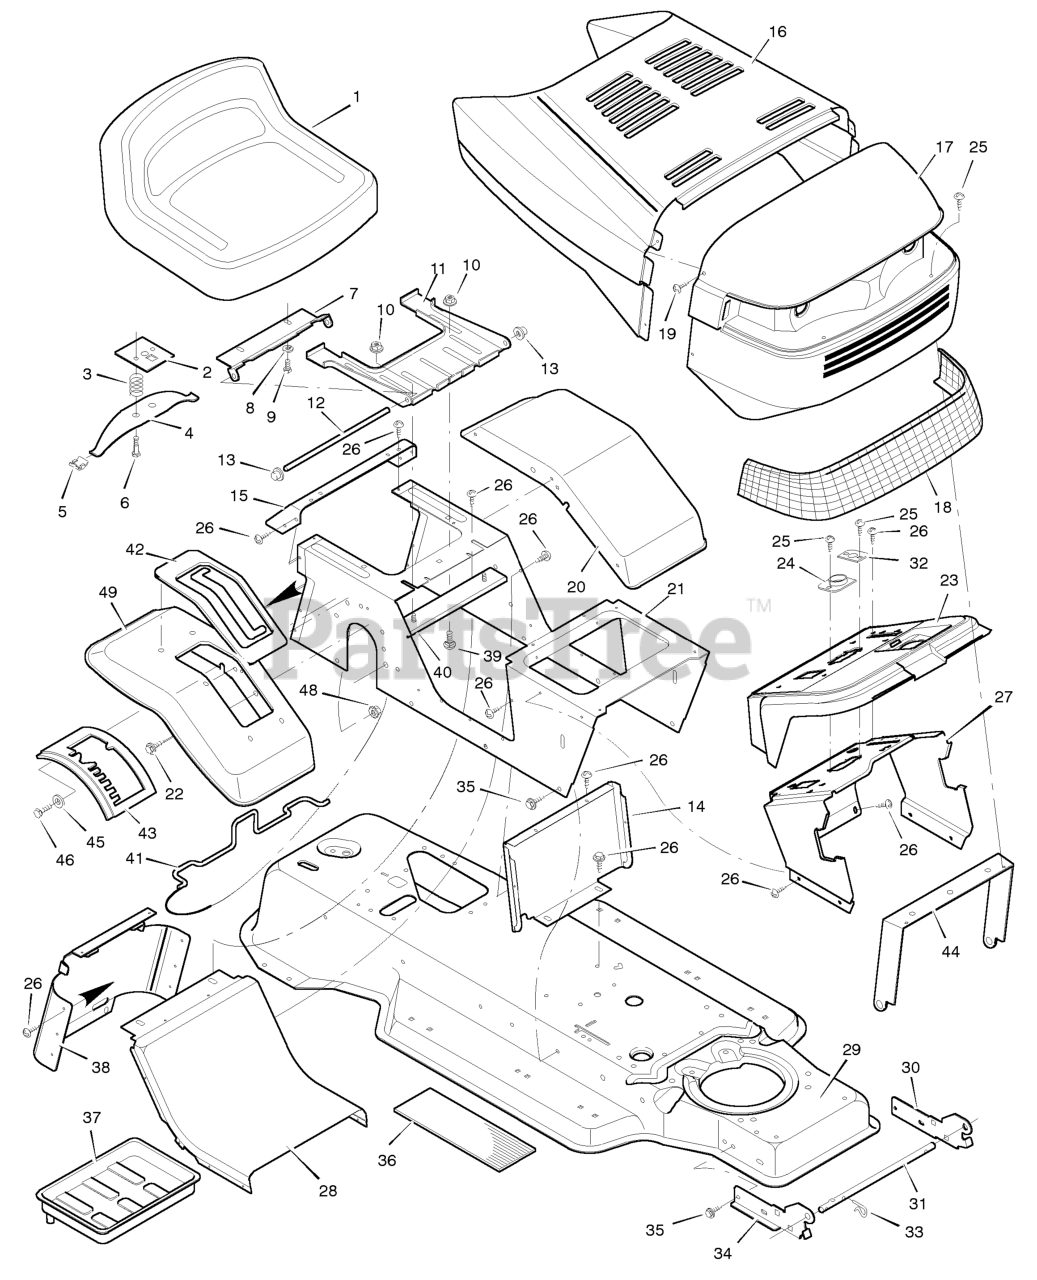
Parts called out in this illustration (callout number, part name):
2	Plate Assembly, Switch
3	Spring, Compression
4	Spring, Seat
5	Glide, Spring
6	Bolt, Shoulder
7	Support, Seat
8	Lockwasher
9	Bolt, Hex
10	Locknut, Flange
11	Bracket, Pivot
12	Rod, Pivot
13	Cap, Push On
14	Insert, Front
15	Fender, Apron
16	Hood
17	Grille Assembly
21	Console Assembly
23	Dash Panel
24	Bearing, Steering
26	Screw
27	Support, Dash
28	Insert, Rear
29	Frame Assembly
30	Bracket, Left Grille
31	Rod, Pivot
32	Bearing
33	Pin, Hair
34	Bracket, Right Grille
37	Tray, Battery
38	Cap, Console
39	Bolt
40	Channel Assembly
41	Clamp, Battery
42	Cover, Shift
43	Gate, Shift
44	Brace, Grille
46	Bolt, Hex
48	Locknut
49	Fender, SOG
